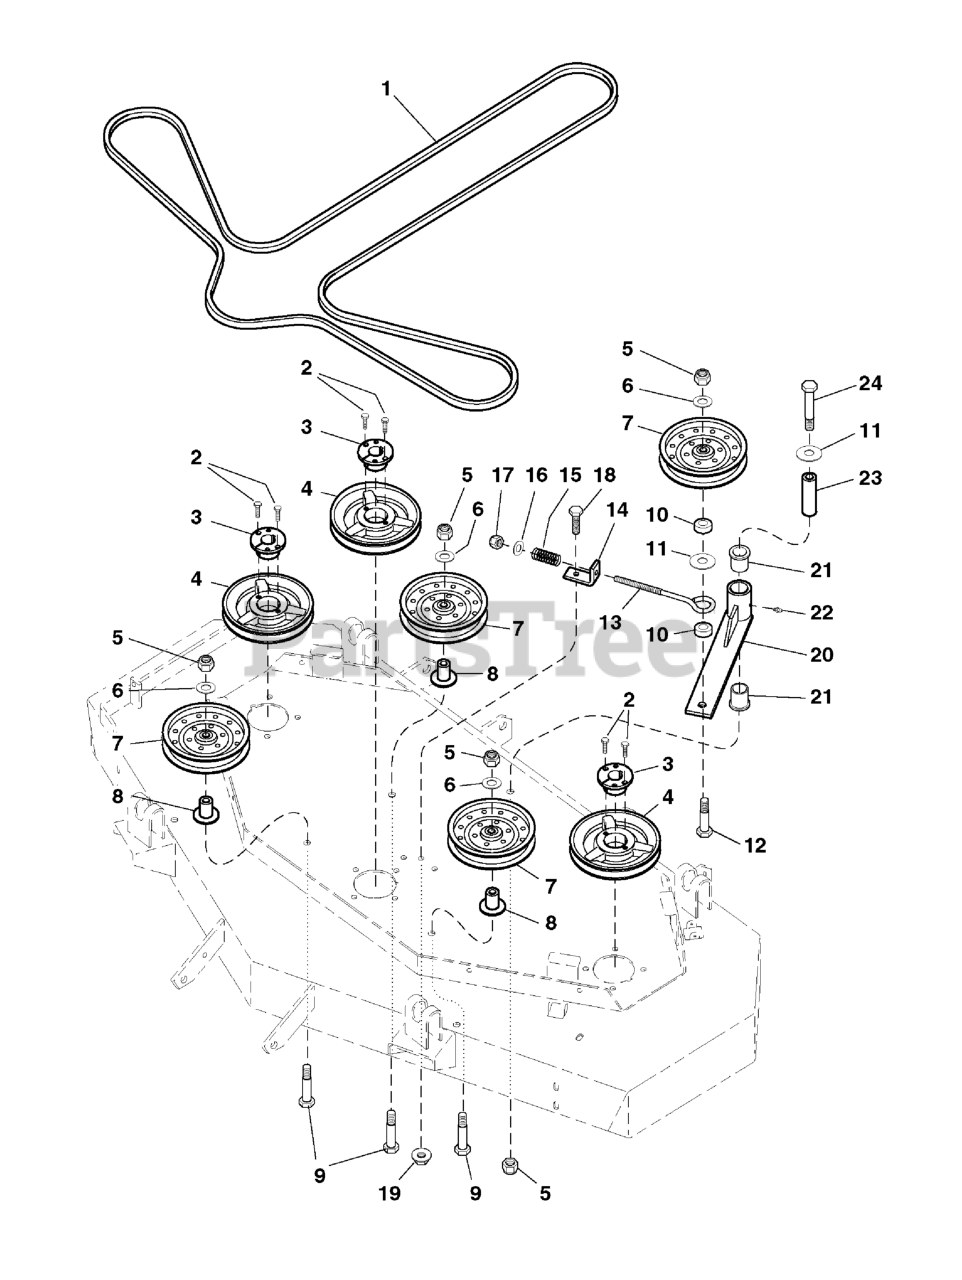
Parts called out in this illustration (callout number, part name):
1	BELT, 61" Deck
2	BOLT, 1/4-20 X 1" GD5 CZ
3	BUSHING, Tapered Hub
4	PULLEY, Spindle
5	NUT, 1/2-13 HEX NYLON LOCK
6	WASHER, 1/2 SAE
8	IDLER PULLEY MOUNT
9	BOLT, 1/2-13 X 3-1/2, HEX HD, GD5, CZ (SV)
10	SPACER, .52 x 1.00 x .44
11	WASHER, 1/2" USS
12	BOLT, 1/2-13 X 3" GD5 CZ
13	EYEBOLT, 3/8" x 8"
14	SPRING ANCHOR
15	SPRING, Compression
16	WASHER, 3/8 SAE
17	NUT, 3/8-16 HEX NYLON LOCK
18	BOLT, 3/8-16 X 1" GD5 CZ
19	NUT, 3/8-16 Hex Serrated Flange
20	IDLER ARM
21	BUSHING, FLANGE
22	GREASE FITTING
23	SPACER, .52 x 1.00 x 3.50
24	BOLT, 1/2-13 x 4-1/2
